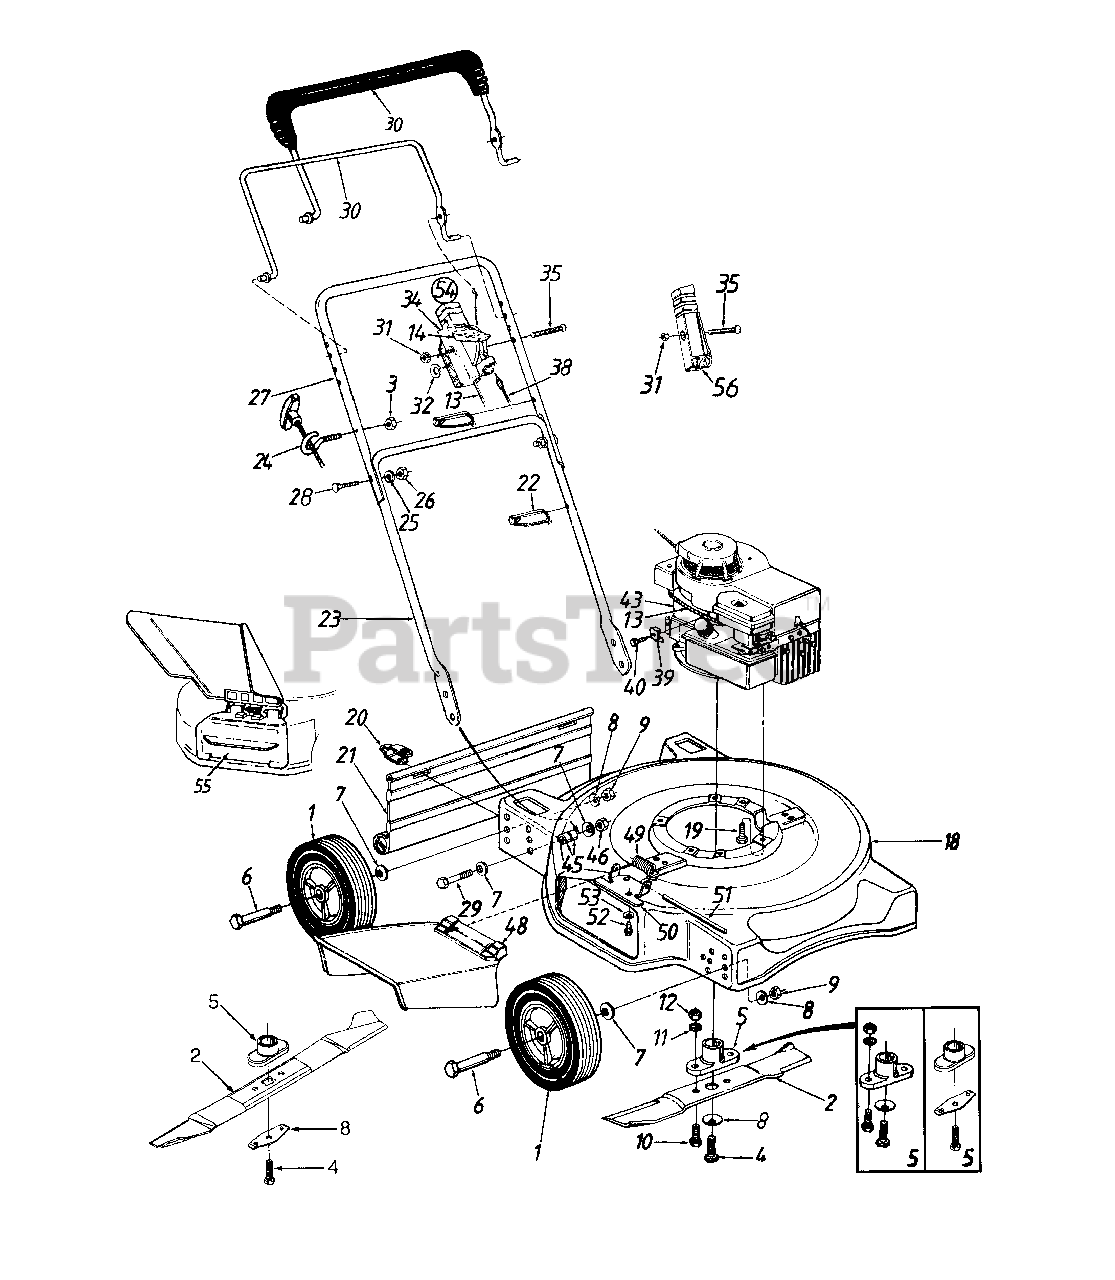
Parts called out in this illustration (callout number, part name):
1	Wheel Ass'y. Comp.
2	20" Blade
3	Hex L-Nut 1/4-20 Thd.
4	Hex Bolt 3/8-24 x 1.5" Lg.
5	Blade Adapter Kit
6	Axle Bolt
7	Bell-Wash. .380" I.D. x .88"
8	Bell-Wash. .39" I.D. x 1.13"
9	Hex Nut 3/8-16 Thd.
10	Hex Bolt 3/8-24 x 1" Lg.
11	L-Wash. 3/8" I.D.
12	Hex Nut 3/8-24 Thd.
13	Throttle Wire 51" Lg.
14	Throttle Lever
18	20" Deck Ass'y.
19	Hex Wash. Hd. Scr. 3/8-16 x 1" Lg.
20	Hinge Clip
21	Rear Flap
22	Cable Tie
24	Rope Guide
25	L-Wash. 5/16" I.D.
26	Hex Nut 5/16-18 Thd.
29	Hex Bolt 3/8-24 x 1.5" Lg.
31	Hex L-Nut 1/4-20 Thd.
32	Spr. Wash. .66" I.D
34	Throttle Body
35	Oval C-Sunk Scr.
38	Control Cable
39	Casing Clamp (B&S)
40	Hex Wash. Hd. Scr. #10-32 x .62 Lg
43	Engine
45	Spacer .391" I.D. x .375" Lg.
46	Hex L-Nut 3/8-24 Thd.
48	Chute Deflector Ass'y.
49	Torsion Spring
50	Adapter Plate
51	Hinge Pin
52	Hex Self-Tap Scr. 1/4-20 x .5"
53	Bell-Wash. 1/4" I.D.
54	Throttle Box Comp.
55	Mulching Plug
56	Control Cable Box
